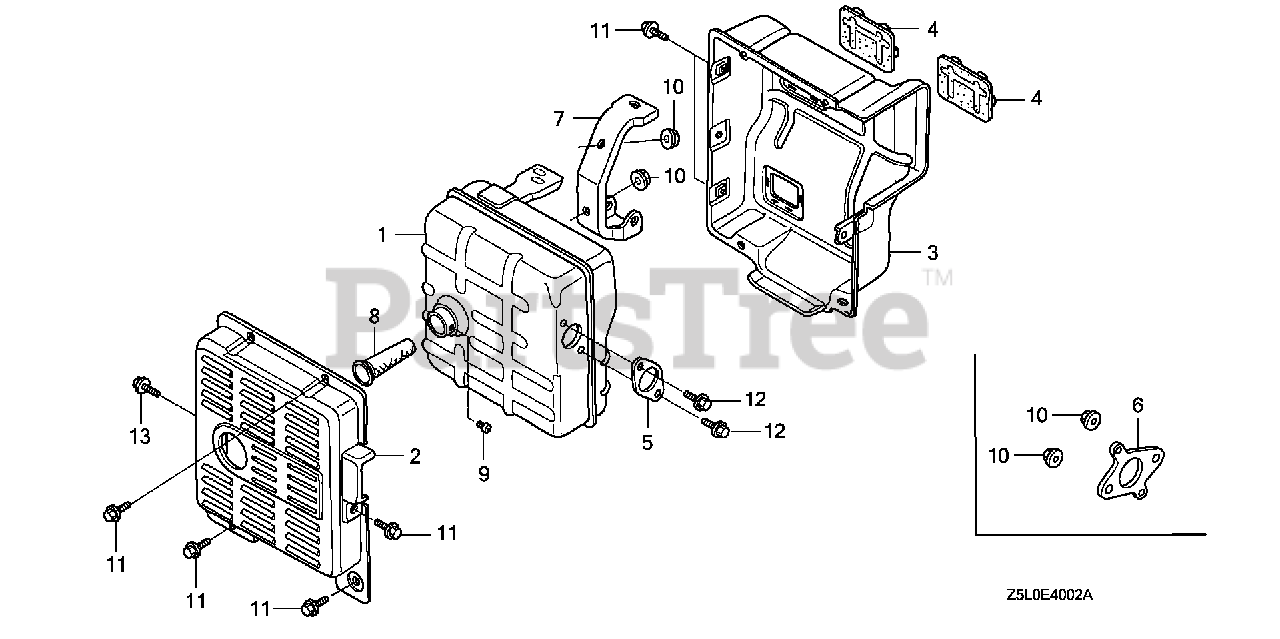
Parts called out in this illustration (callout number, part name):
1	MUFFLER (TSURUMI)
2	PROTECTOR, MUFFLER (OUTER)
3	PROTECTOR, MUFFLER (INNER)
4	SEAL, MUFFLER PROTECTOR
5	GASKET, EX. PIPE
7	STAY A, MUFFLER (TSURUMI)
8	ARRESTER, SPARK
9	SCREW, TAPPING (4X8)
12	BOLT, FLANGE (8X20)
